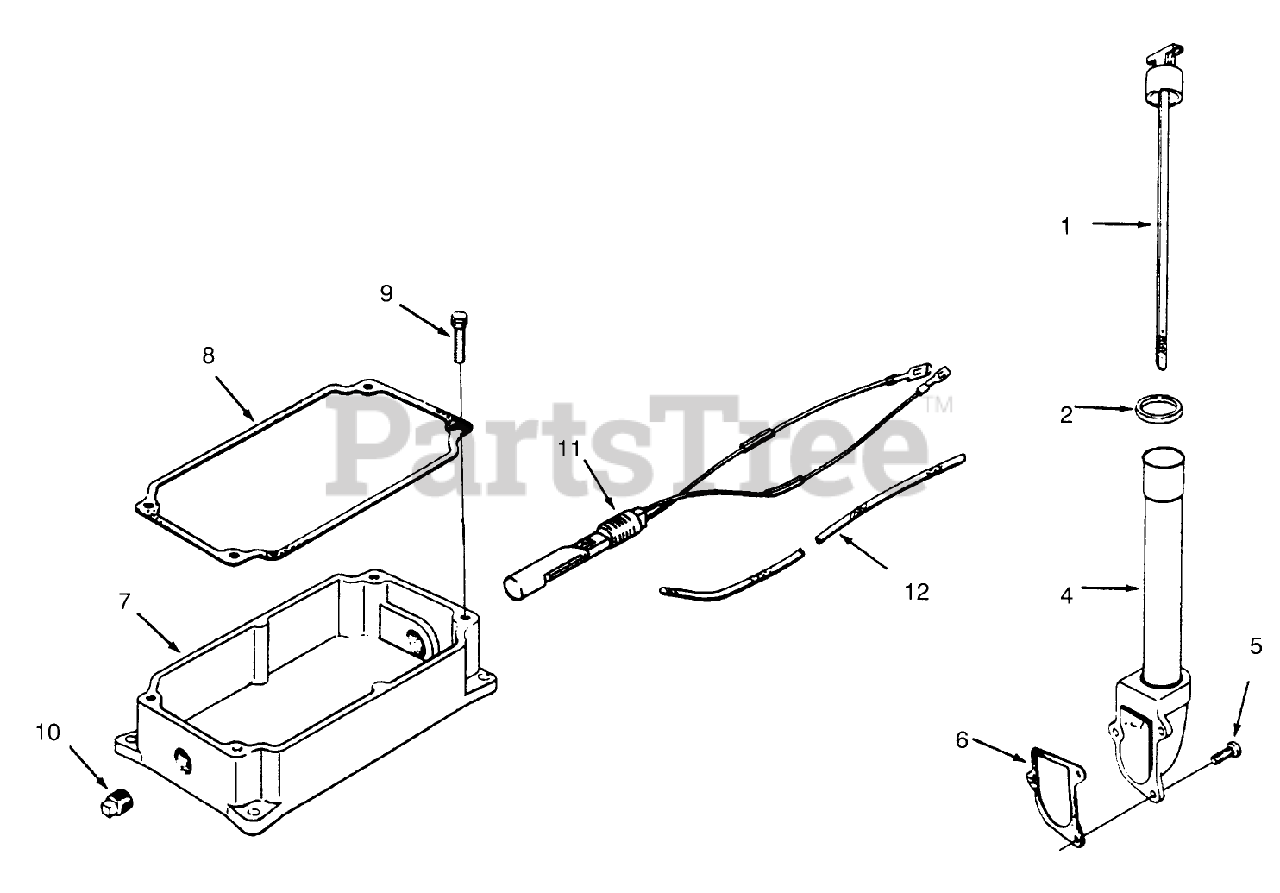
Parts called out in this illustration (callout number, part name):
1	KOHLER 47-038-27
2	KOHLER 41-153-01
4	KOHLER 47-029-06
5	KOHLER X-131-2
6	KOHLER 237064
7	KOHLER 45-199-05
8	KOHLER 235057
9	KOHLER X-159-3
10	KOHLER X-75-10
11	KOHLER 47-099-04
12	KOHLER 25-431-02
